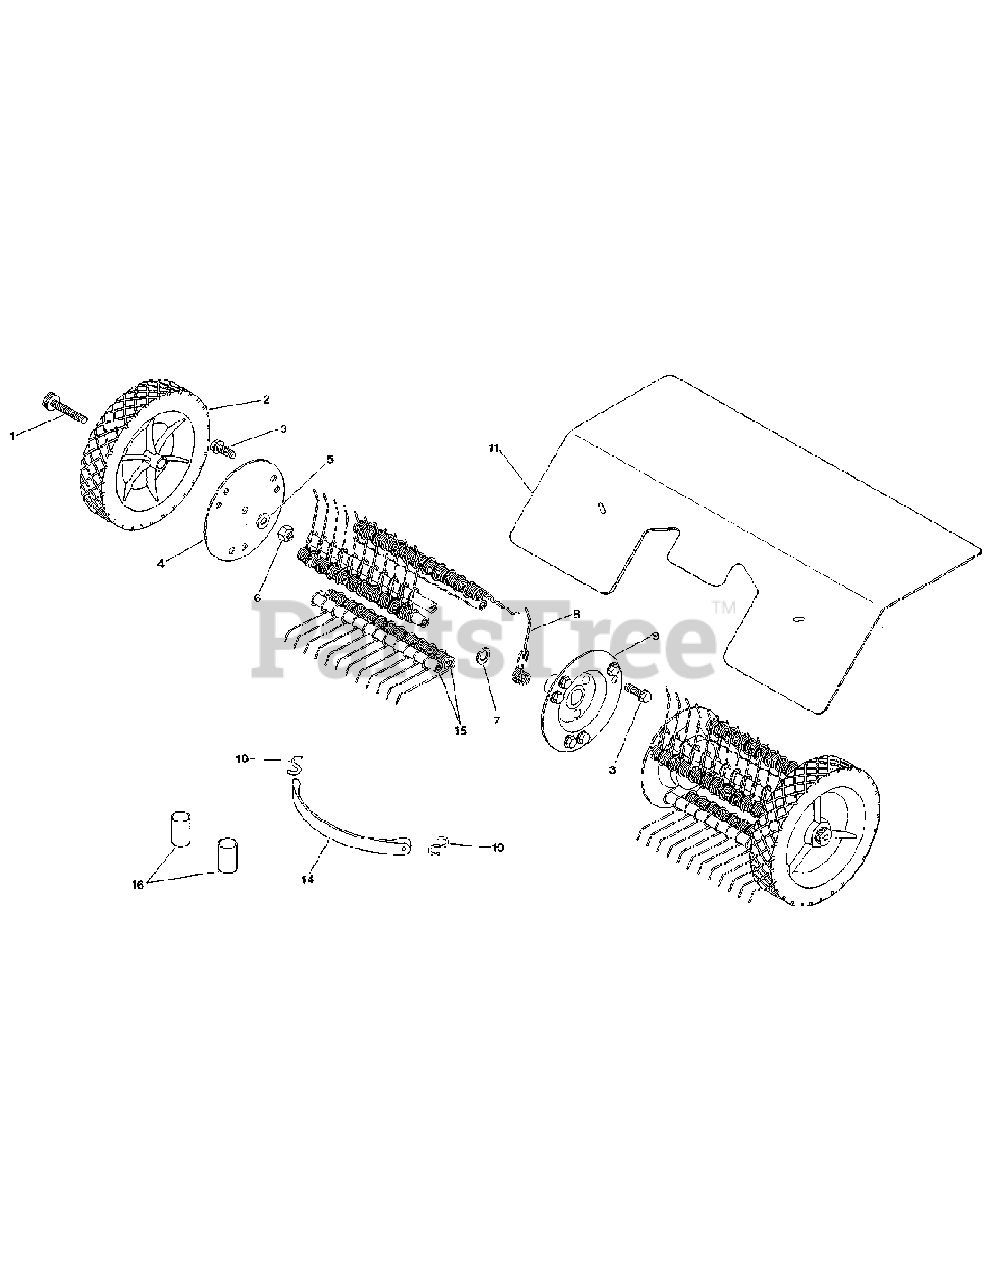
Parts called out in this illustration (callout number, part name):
1	Bolt, Socket Hd., 3/8-16 x 1-1/2
2	Wheel/Tire Assembly
3	Whiz Bolt, 5/16-18 x 3/4
4	End Cap - outer
5	Lockwasher, 3/8
6	Hex Nut, 3/8-16
7	Washer, Flat, 1/2
8	Tine Kit (contains 5 spring tines)
9	End Cap - inner
10	"S" Hook
11	Debris Shield
14	Strap, Debris Shield
15	Bar, tine retaining/tine attachment
